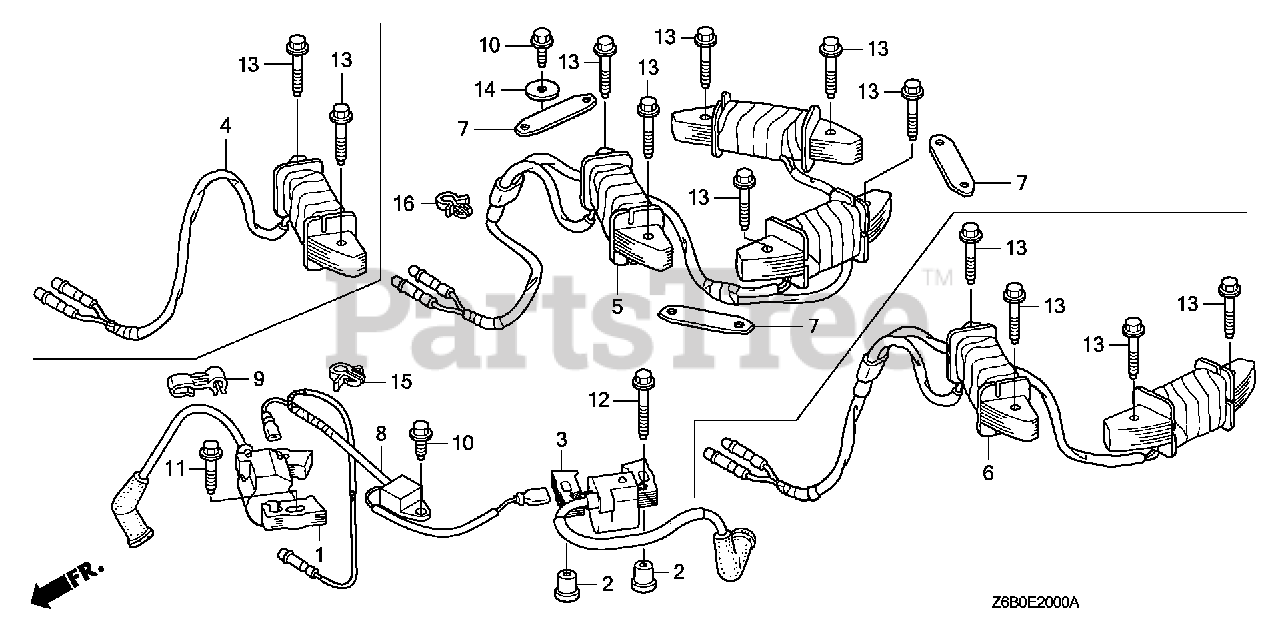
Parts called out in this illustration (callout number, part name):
1	COIL ASSY., IGNITION (#1)
2	COLLAR, IGNITION COIL
3	COIL ASSY., IGNITION (#2)
6	COIL ASSY., CHARGE (12V/12A)
8	DIODE ASSY., ENGINE STOP
9	CLAMP, CENTER WIRE
10	BOLT, FLANGE (6X12) (CT200)
11	BOLT, FLANGE (6X28) (CT200)
12	BOLT, FLANGE (6X45) (CT200)
13	BOLT, FLANGE (6X32) (CT200)
14	WASHER, TANK SETTING
15	CLIP, WIRE HARNESS (6MM) (WHITE)
16	CLIP, WIRE HARNESS
